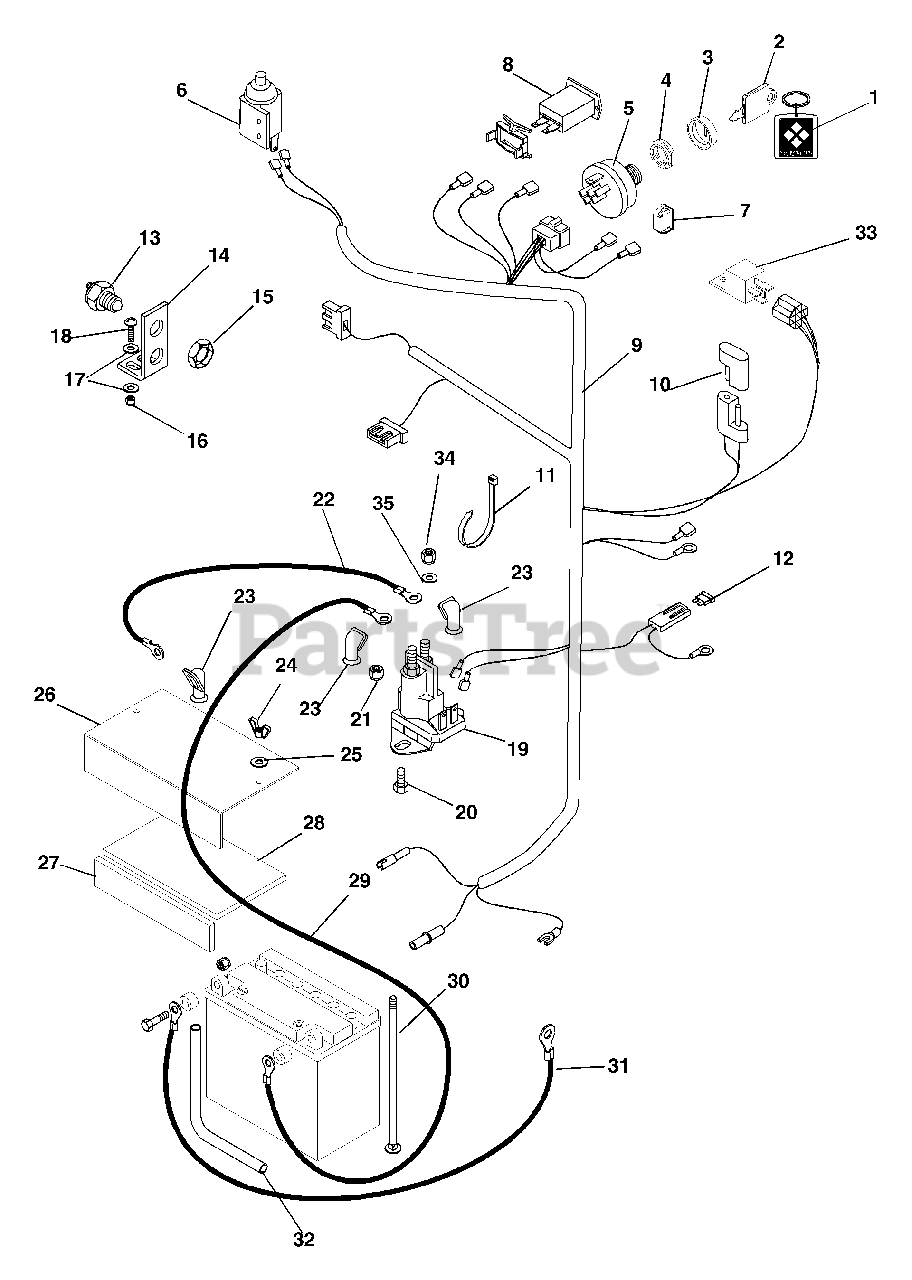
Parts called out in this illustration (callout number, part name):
1	KEY CHAIN
2	KEY -W/CAP
3	CAP - IGNITION SWITCH
4	NUT- PANEL .562-24 GRECO
5	SWITCH ASSEMBLY
6	SWITCH-SINGLE POLE N.O.W/COVER
7	LIGHT, INDICATOR (RED)
8	METER, HOUR W/MAINTENANCE
9	WIRE HARNESS, PRO-150 16 B&S
10	MOLDED DIODE PLUG 1 AMP
11	TIE WRAP, BLACK LG 7.31
12	FUSE, 30 AMP.
13	SWITCH-NEUTRAL START N.O.
14	BRKT,INTERLOCK SWITCH
15	NUT-STAMPED .56-18
16	@NUT-LK-NYL 10-24 W/INSRT YWZC
17	@WSHR-FL-STL.219X.50X.049 YWZC
18	@SCR-MCH 10-24X.75 HWH YWZC
19	SOLENOID
20	@BLT-HEX .25-20X.50 GR5 YWZC
21	@NUT-LK-CTR .25-20 YWZC
22	STARTER CABLE 6.75"
23	BOOT, INSULATOR
24	NUT-LK WING .250-20 YWZC
25	@WSHR-FL-STL.281X.62X.065 YWZC
26	CVR,BATTERY
27	PAD,BATTERY
28	PAD,BATTERY
29	START CABLE 22"
30	@BLT-RDHDSQNK .25-20X7.00 G2YZ
31	CABLE, NEGATIVE BATTERY 24.00
32	BATTERY,12 VOLT
33	Relay
34	NUT-JAM .31-24 YWZC
35	WSHR-LOCK INT .31 YWZC
